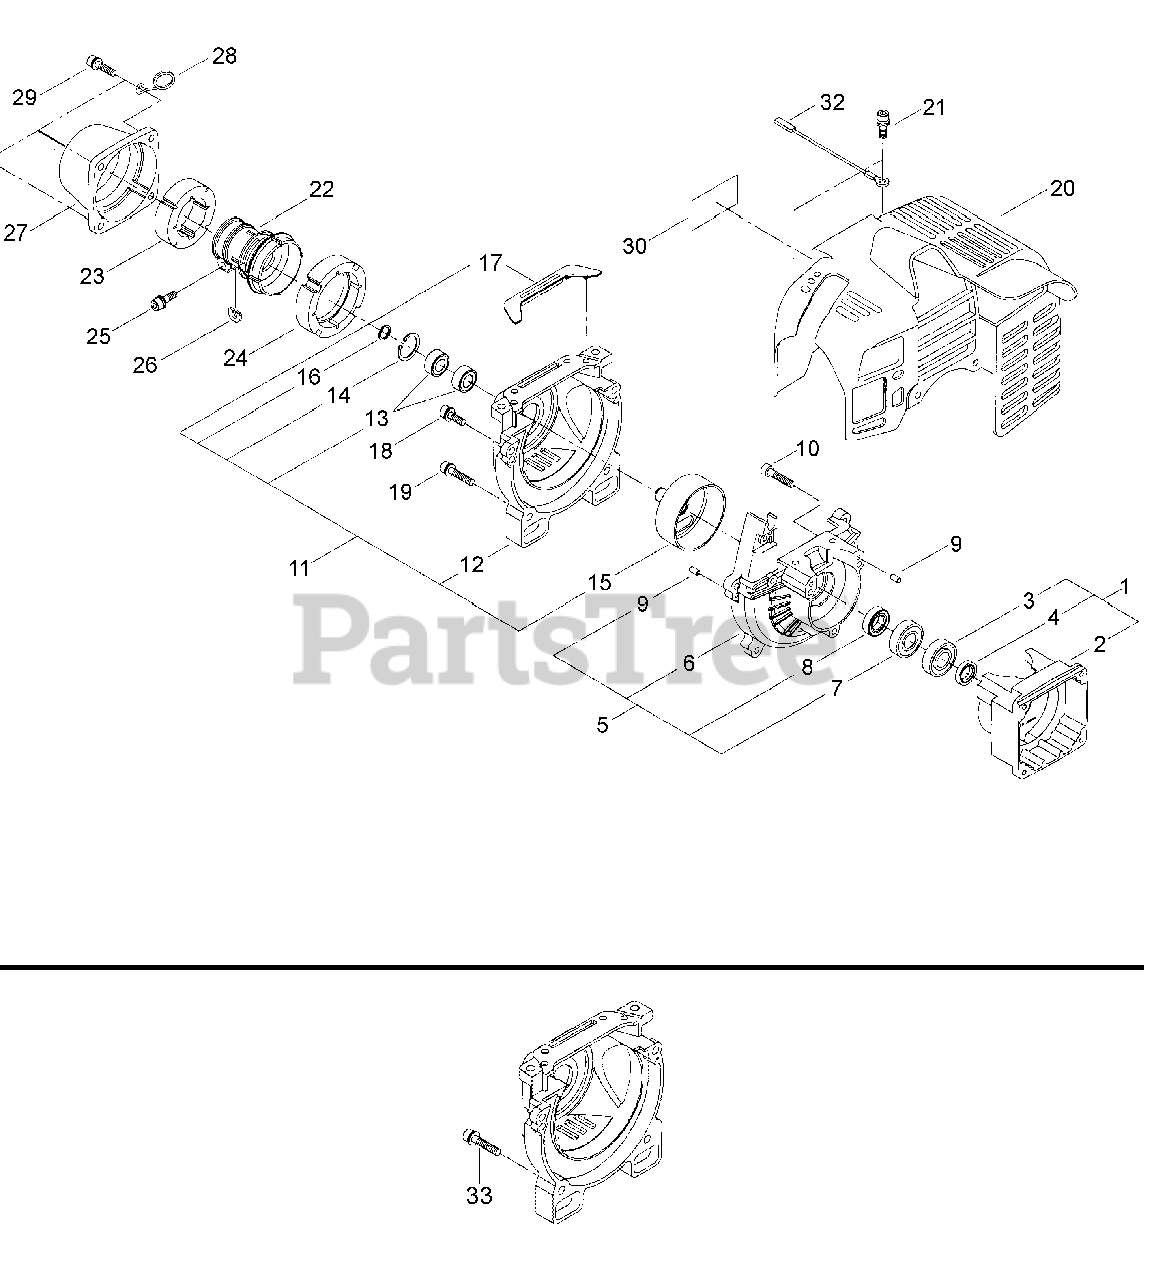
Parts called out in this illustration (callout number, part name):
1	CRANKCASE ASSY - REAR
2	CRANKCASE - REAR
3	BEARING, BALL - 6001C3
4	SEAL, OIL
5	CRANKCASE ASSY - FRONT
6	CRANKCASE - FRONT
7	BEARING, BALL - 6001C3
8	SEAL, OIL - 12
9	PIN - LOCATING
10	SCREW - 5X25
11	FAN COVER ASSY
12	COVER, FAN
13	BEARING
14	RING, RETAINING - 26
15	DRUM, CLUTCH
16	RING, RETAINING
18	SCREW - 5X16
19	SCREW - 5X30
20	COVER, CYLINDER
21	SCREW - 5X16
22	CLAMP, MAIN PIPE
23	CUSHION - FRONT
24	CUSHION - REAR
25	SCREW - 5X25
26	SHIM
27	CAP
28	GUIDE, CABLE
29	SCREW - 5X20
30	LABEL - MODEL
32	LEAD - GROUND
33	SCREW - 5X25
